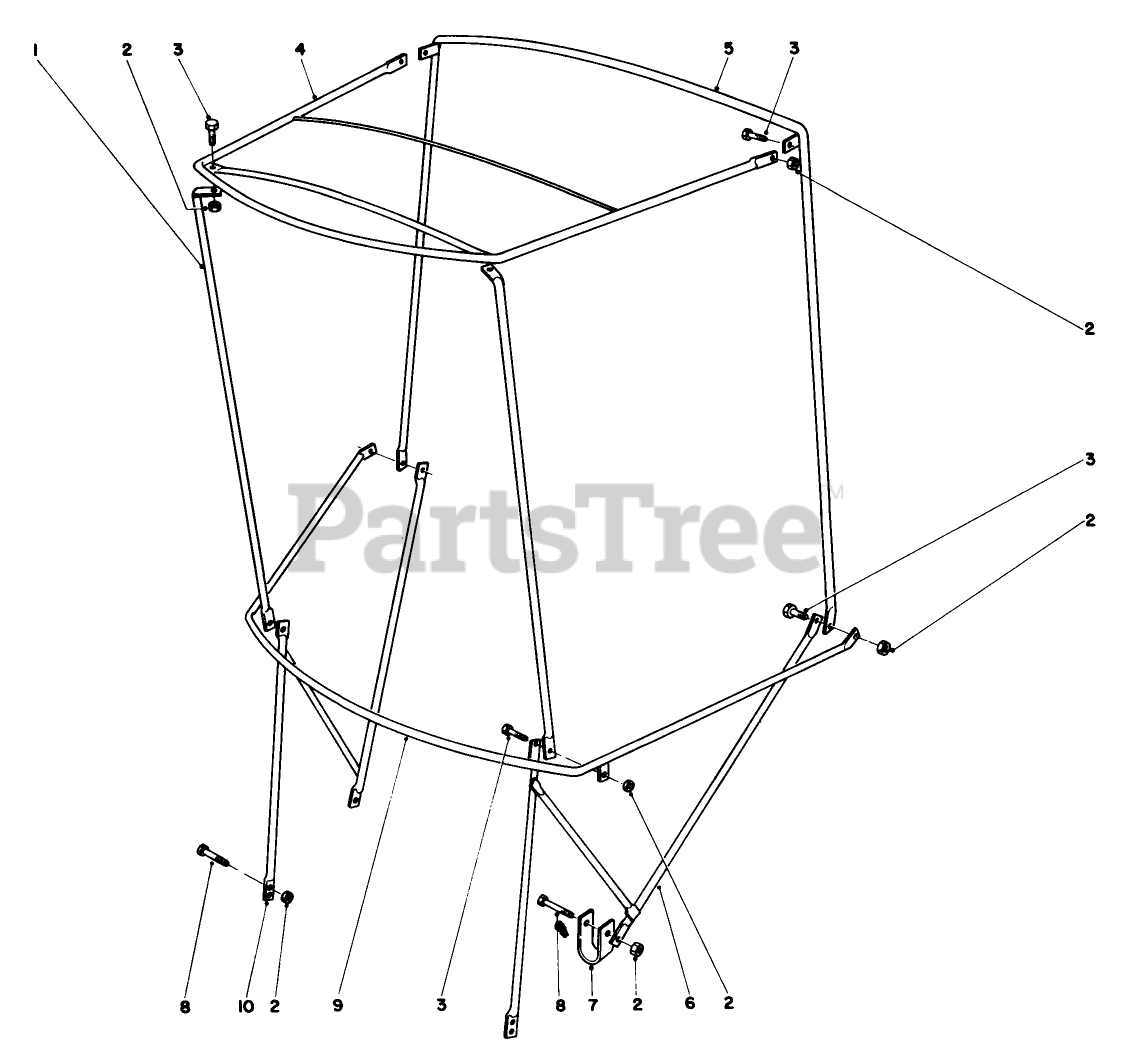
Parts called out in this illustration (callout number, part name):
2	NUT-HEX, SIDE DEFORM
3	SCREW-HH
8	SCREW-HH
10	Attaching Bracket R.H.
